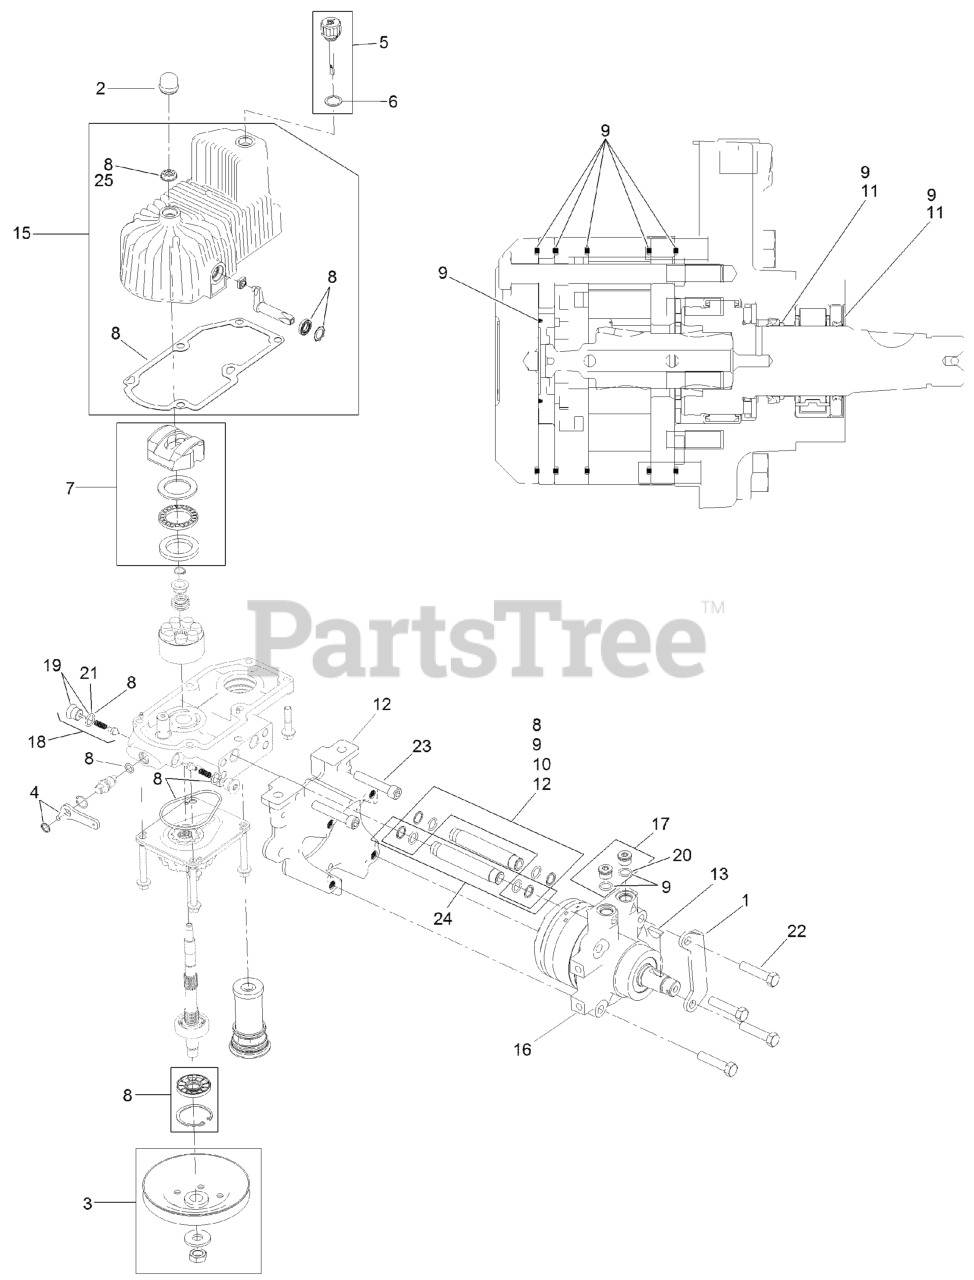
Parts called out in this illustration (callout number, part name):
1	MOUNT-SHOE, HORSE
2	COVER-SHAFT, HYDRO
3	PULLEY KIT
4	HANDLE-BYPASS VALVE, HYDRO
5	DIPSTICK-HYDRO W/GASKET
6	GASKET-DIPSTICK, HYDRO
7	SWASH BLOCK KIT
8	PUMP SEAL KIT
9	MOTOR SEAL KIT
10	TUBE SEAL KIT
11	OUTPUT SHAFT SEAL KIT
12	NOSE CUP-UHT
13	KEY-WOODRUFF
15	HOUSING-HYDRO, RH
16	MOTOR-HYDRAULIC RH 240CC
17	MAGNETIC PLUGS SERVICE KIT
18	CHECK VALVE ASM
19	PLUG-CHECK (W/O-RING)
21	O-RING-CHECK VALVE
22	SCREW HH
23	SCREW-HSH
24	HYDRAULIC TUBE KIT
25	SEAL-FAN DRIVE
26	KIT, PUMP SECTION 12CC RH NO FAN
27	KIT, ROTATING GRP 12CC RH
